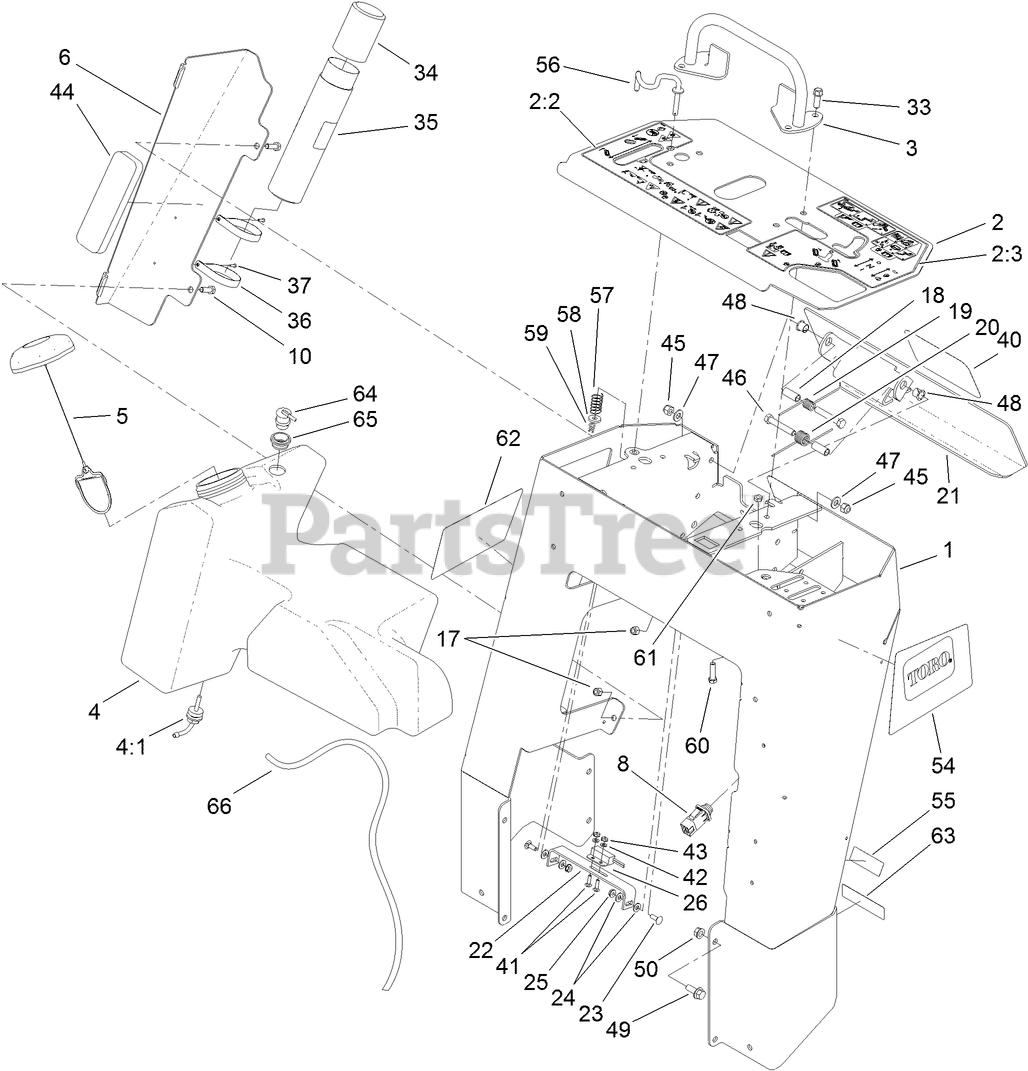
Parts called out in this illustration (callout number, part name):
2	PANEL-CONTROL
2:2	DECAL-CONSOLE, RH
2:3	DECAL-CONSOLE, LH
3	BAR-REFERENCE
4	TANK-FUEL
4:1	FITTING-FUEL, BULKHEAD
5	CAP-FUEL, RATCHETING
6	BRACKET-COVER, TANK
8	SWITCH-PLUNGER
10	SCREW-HH
17	NUT-LOCK, NI
18	SPACER-SPRING
19	SPRING-TORSION, LH
20	SPRING-TORSION, RH
21	PLATE-REVERSE
22	PLATE-SWITCH
23	BOLT-CARR
24	WASHER-FLAT
25	NUT-KEPS
26	SWITCH-PROXIMITY
33	SCREW-TAPTITE
34	CAP-HOUSING
35	TUBE-MANUAL
36	CLAMP-R
37	RIVET-POP
41	SCREW-CARR
42	WASHER-FLAT
43	NUT-KEPS
44	PAD-FOAM
45	NUT-LOCK, NI
46	SCREW-HH
47	WASHER-FLAT
48	BUSHING-NYLINER
49	SCREW-HHF
50	NUT-FLANGE
54	DECAL-SIDE, LH
55	DECAL-INFO
56	ROD-INTERLOCK
57	SPRING-CONTROL
58	WASHER-FLAT
59	PIN-COTTER
60	SCREW-HH
61	NUT-JAM
62	DECAL-SIDE, RH
63	DECAL-ARRESTER, SPARK
64	VALVE-ROLLOVER
65	GROMMET
66	HOSE-VENT, TANK
